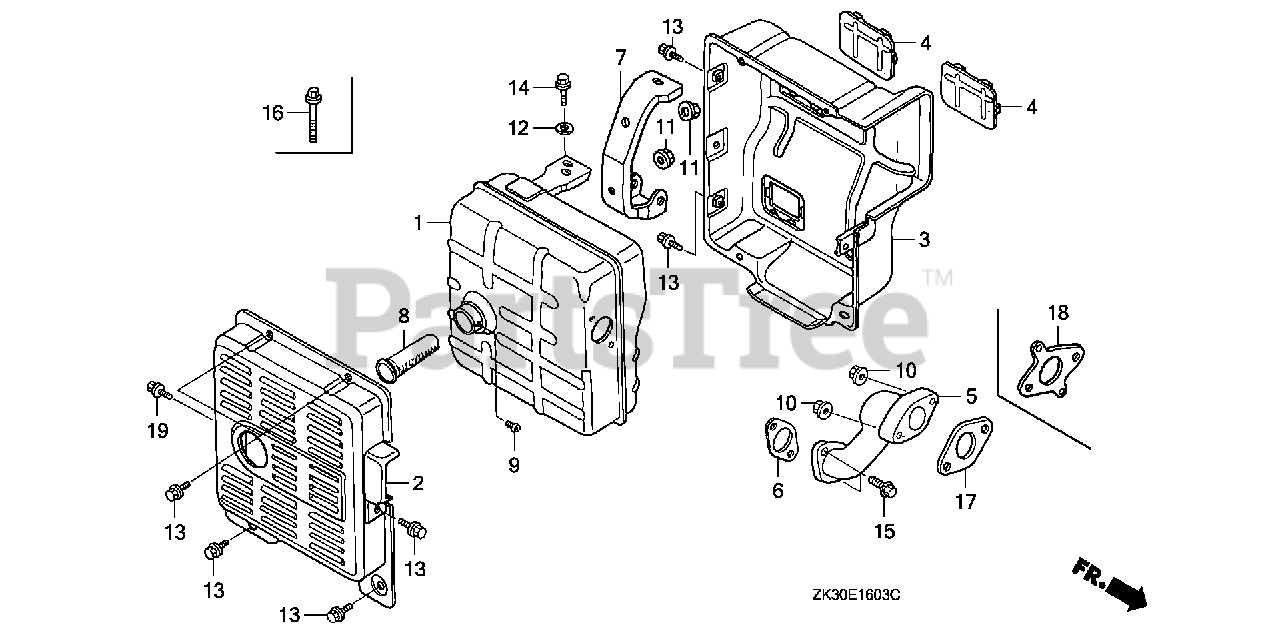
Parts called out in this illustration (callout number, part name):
1	MUFFLER (SANKEI)
2	PROTECTOR, MUFFLER (OUTER)
3	PROTECTOR, MUFFLER (INNER)
4	SEAL, MUFFLER PROTECTOR
6	GASKET, EX. PIPE
8	ARRESTER, SPARK
9	SCREW, TAPPING (4X8)
10	NUT, FLANGE (8MM)
13	BOLT, FLANGE (6X10)
13	BOLT, FLANGE (6X12)
15	BOLT, FLANGE (8X20)
17	GASKET, EX. PIPE
19	BOLT, FLANGE (6X12)
